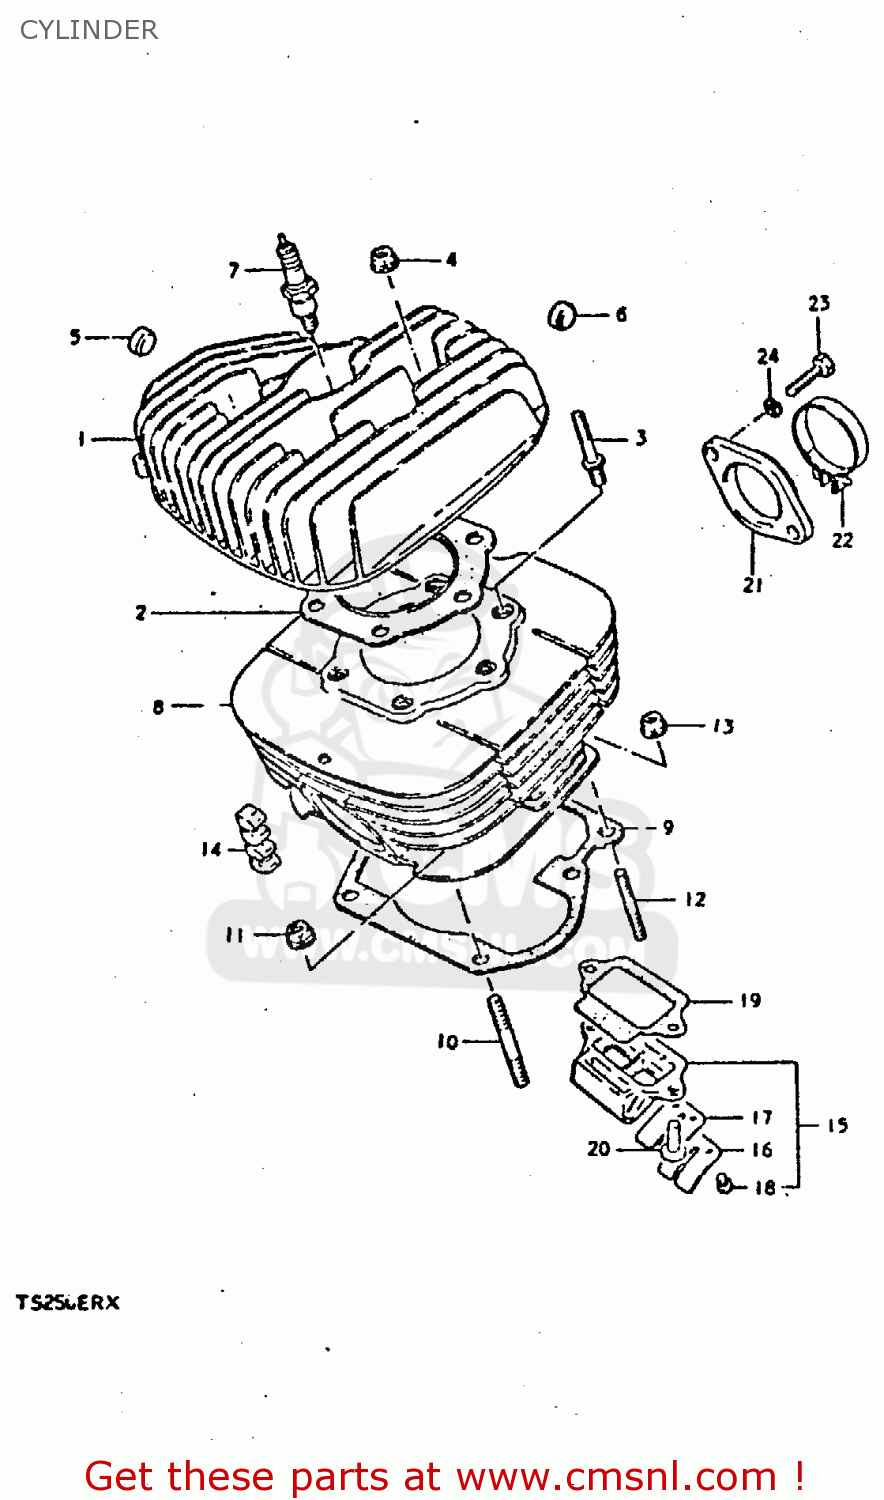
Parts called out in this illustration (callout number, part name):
1	HEAD,CYLINDER
2	GASKET,CYLINDER HEAD (NAS)
3	BOLT,STUD
4	NUT
5	PAD,CYLINDER
6	PAD,CYLINDER HEAD
7	SPARK PLUG
8	CYLINDER
9	GASKET,CYLINDER (MCA)
10	STUD 10X25
11	NUT
12	STUD 8X25
13	NUT
14	RUBBER PAD
15	VALVE ASSY,REED
16	STOPPER,REED VALVE
17	VALVE,REED
18	SCREW,REED VALVE
19	GASKET,REED VALVE (MCA)
20	SCREW
21	PIPE,INTAKE
22	CLAMP
23	BOLT, UPPER
24	LOCK WASHER
